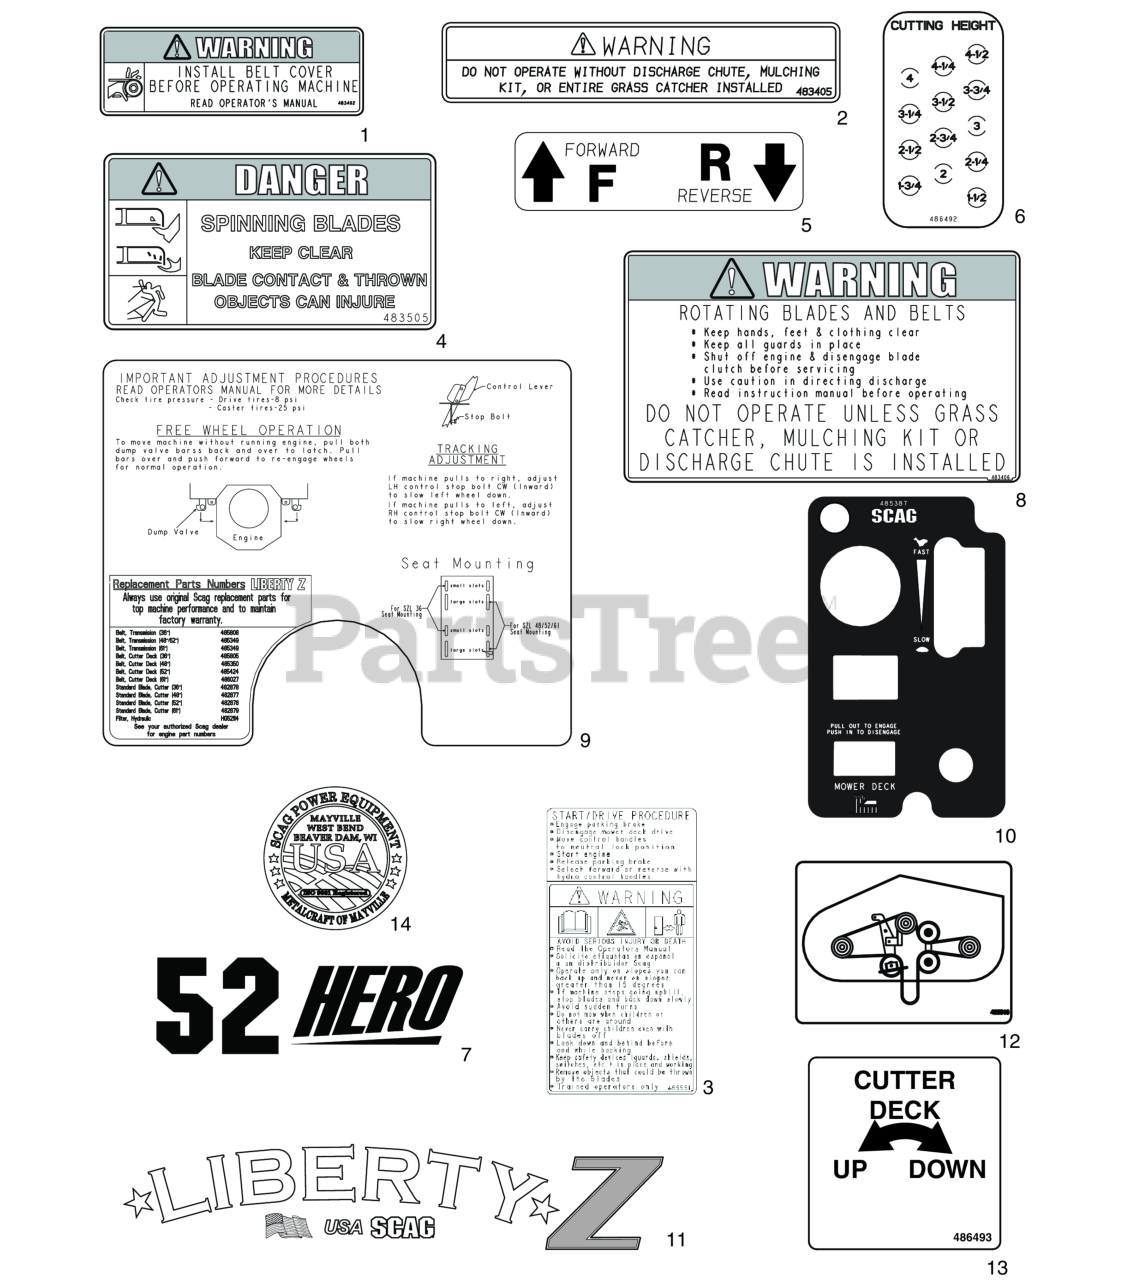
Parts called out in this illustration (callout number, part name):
1	Decal, Warning - Belt Cover
2	Decal, Warning-Discharge
3	Decal, Start/Drive
4	Decal, Spinning Blades
5	Decal, Traction Control
6	Decal, Height of Cut
7	Decal, 48 Hero
8	Decal, Warning - Rotating Blades
9	Decal, Adjustments - SZL
10	Decal, Instrument Panel - SZL (48 & 52)
11	Decal. Liberty Z - Fuel Tank
12	Decal, SZL / SFZ / SPZ Belt Routing
13	Decal, Cutter Deck Lift Control
14	Decal, Metalcraft - USA
